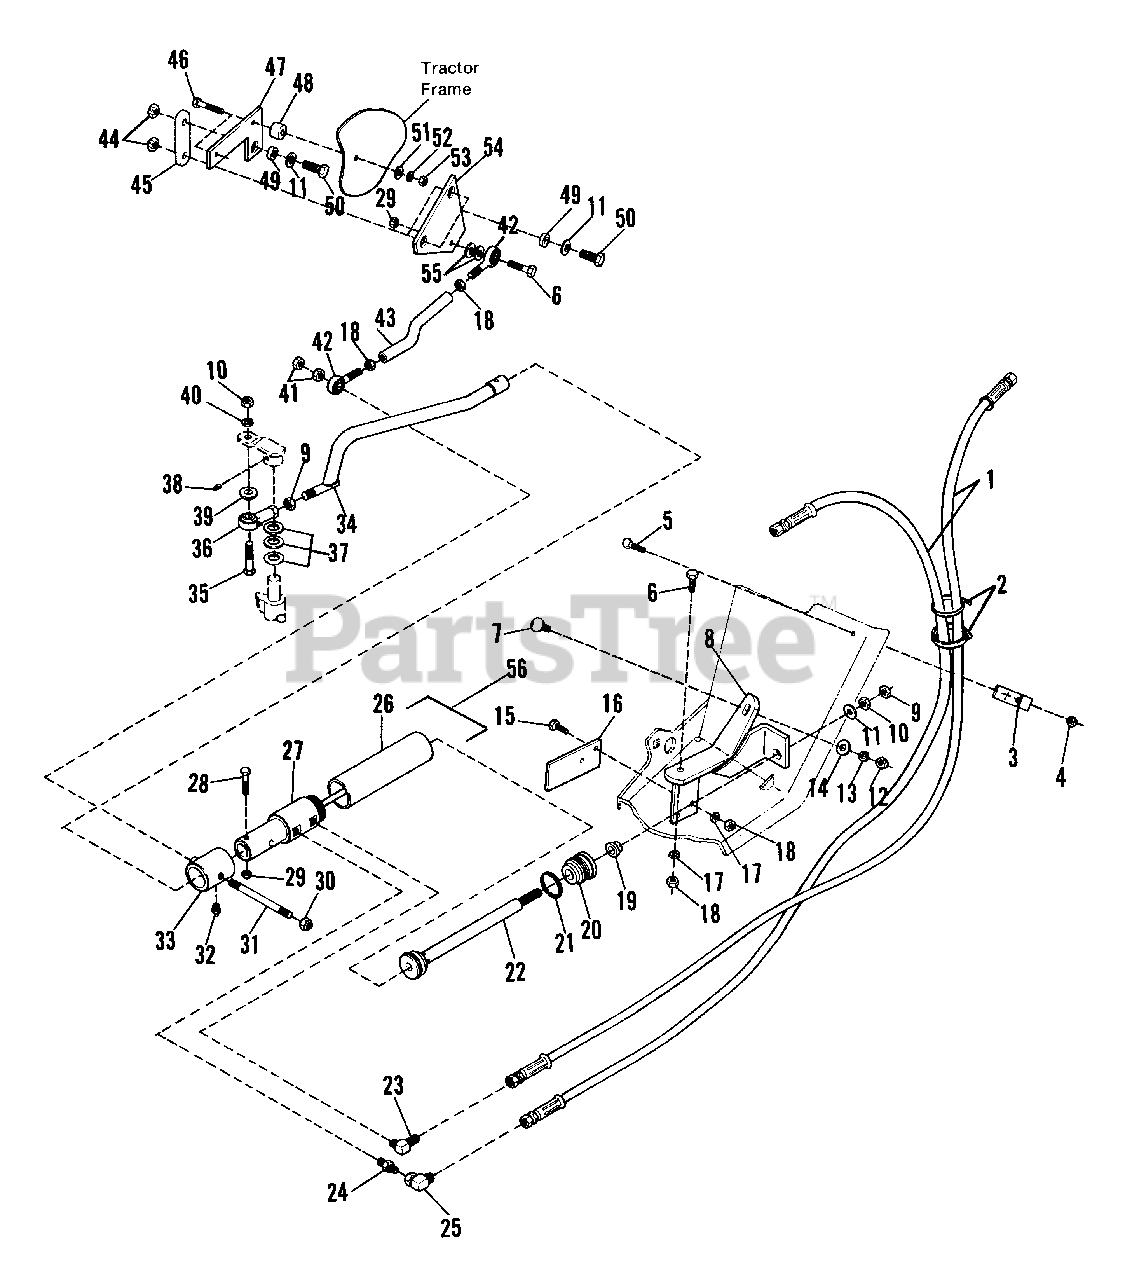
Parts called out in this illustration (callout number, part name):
1	HOSE, Hydraulic
2	TIE, Plastic
3	CLAMP, Hose
4	LOCKNUT, 1/4 x 20
5	BOLT, 1/4-20 x 1-1/4
6	BOLT, 3/8-14 x 1-1/4
7	BOLT, 7/16-14 x 1-1/2
8	BRACKET, Footrest
9	NUT, Jam, 1/2-20
10	NUT, 1/2-20
11	WASHER, 1/2
12	NUT, 7/16-13
13	LOCKWASHER, 7/16
14	WASHER, 7/16
15	BOLT, 3/8 x 24 x 1
16	STOP, Mower (42" mower only)
17	LOCKWASHER, 3/8
18	NUT, 3/8 x 24
19	BUSHING, Flanged
20	GLAND ASSY.
21	LOCKWIRE
22	PISTON ROD ASSY.
23	FITTING, Elbow
25	FITTING, Elbow
26	TUBE, Cylinder
27	VALVE ASSY.
28	BOLT, 3/8 x 2
29	NUT, Self-locking, 3/8-24
30	NUT, Nyloc
31	STUD, Actuator
32	FITTING, Grease
33	SLEEVE, Actuator
34	CYLINDER EXTENSION ASSEMBLY
35	BOLT, 1/2-20 x 1-3/4
36	BALL JOINT, Female, 1/2
37	WASHER, Special
38	SETSCREW, 5/16-18 x 3/8
40	LOCKWASHER, 1/2
41	NUT, 3/8-16
42	BALL JOINT, Male, 3/8
43	LINK, Drag
44	LOCKNUT, 1/2-20
46	BOLT, 5/16-18 x 1-3/4
47	PLATE, Pivot
48	SPACER, "L" Bracket
50	BOLT, 1/2-20 x 1-1/4
51	WASHER, 5/16-16 x 3/4
52	LOCKWASHER, 5/16
53	NUT, 5/16 x 18
54	BRACKET, Carrier
55	WASHER, 3/8-16 x 3/4
56	CYLINDER VALVE ASSY.
